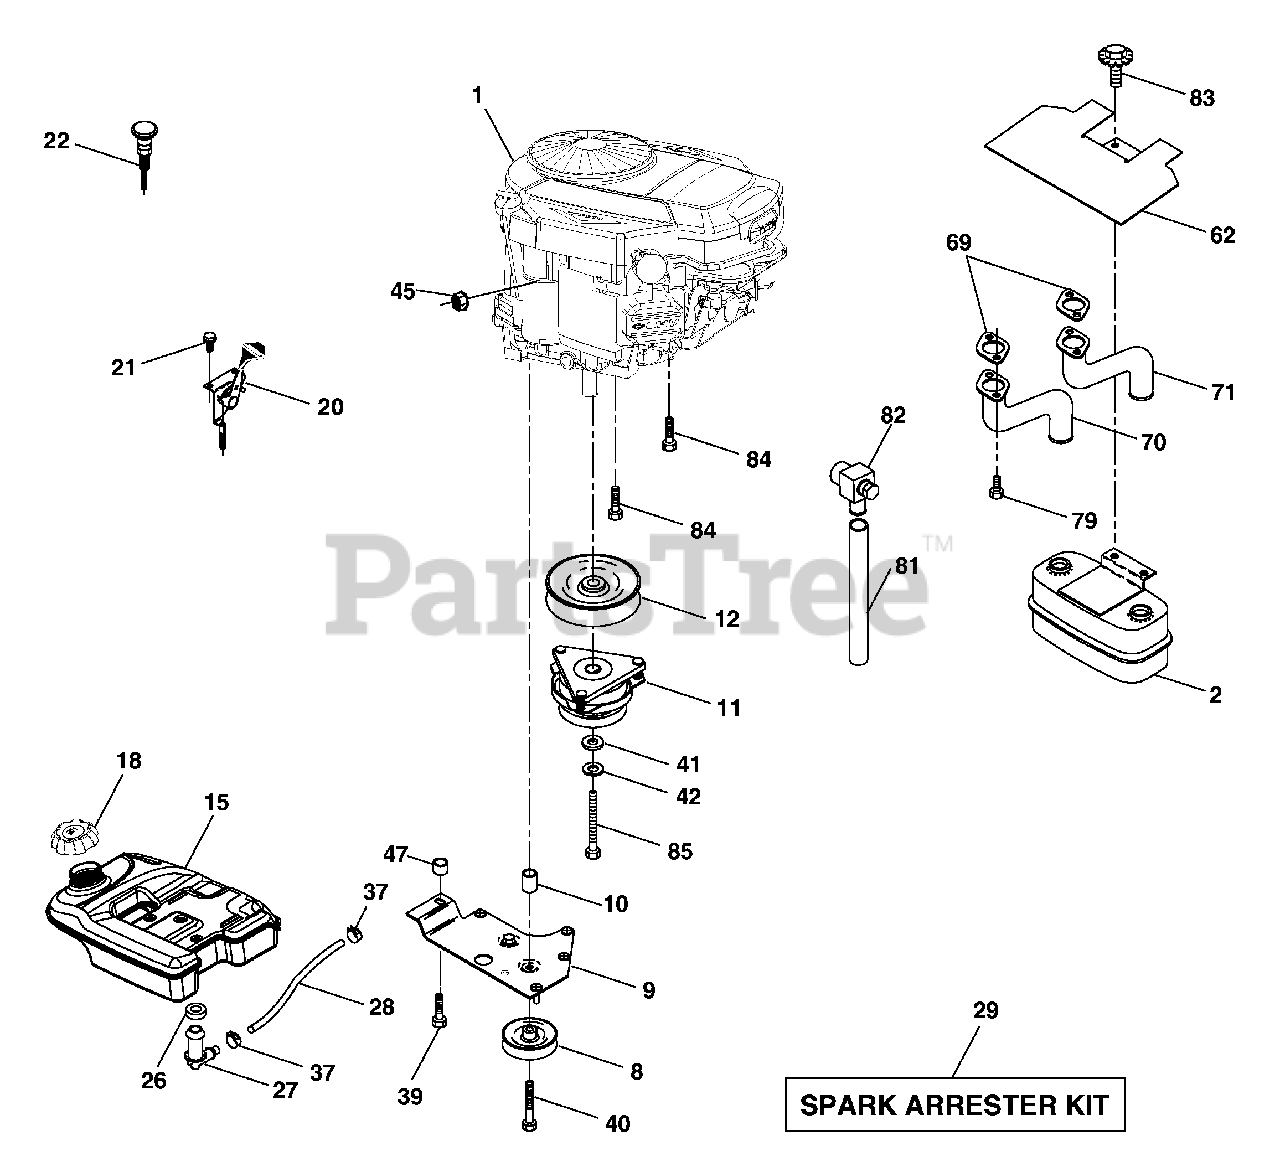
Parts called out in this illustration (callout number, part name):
2	Muffler
8	Pulley V-Idler
9	Keeper Asm. Belt Engine
10	Bushing
11	Clutch Electric
12	Pulley Engine VGT Elect Clutch
15	Tank Fuel Rear 5.0 Yt/Gt
18	Cap Asm
20	Control Throttle
21	Screw 10 x 3/4 Single Lead-Hex
22	Control Choke
26	Bushing
27	Stem Tank Fuel
28	Fuel Line
29	Spark Arrester Kit
37	Clamp Hose
39	Screw TT 3/8-16 x 2-1/4 unc
40	Screw TT 3/8-16 x 4 unc
41	Washer 1-1/2 OD x 15/32 ID x .250
42	Washer Lock 7/16
45	Nut Keps Hex 1/4-20 unc
47	Bushing
62	Shield Heat Muffler
69	Gasket
70	Tube Exhaust LH
71	Tube Exhaust RH
79	Screw Socket Head
81	Tube Drain Oil Easy
82	Valve Oil Drain
83	Bolt 5/16-18 unc x 3/4 W/ Sems
84	Screw 3/8-16 x 1-1/2
85	Bolt Hex 7/16-20 x 3.75 Gr. 5
